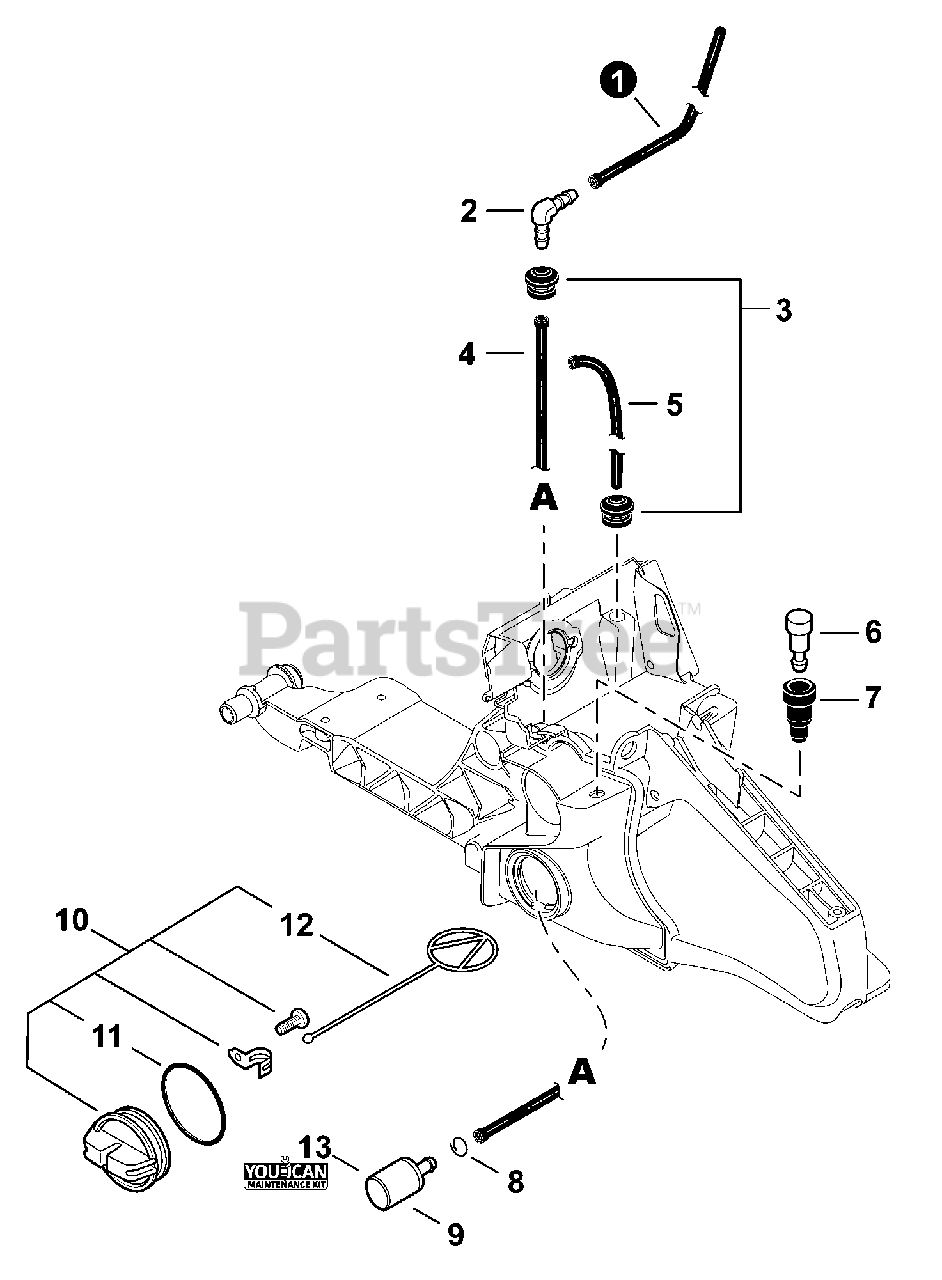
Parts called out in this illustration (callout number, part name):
1	PIPE, FUEL 3×6×135
2	CONNECTOR, PIPE
3	GROMMET
4	PIPE, FUEL 3×5×120 BLACK
5	PIPE, IMPULSE 3×6(8)×160
6	VENT ASSY
7	GROMMET, VENT
8	CLIP Ø6
9	FILTER, FUEL
10	CAP ASSY, FUEL
11	O-RING 29
12	CONNECTOR, CAP L= 60 MM
13	TUNE-UP KIT - YOUCAN™
